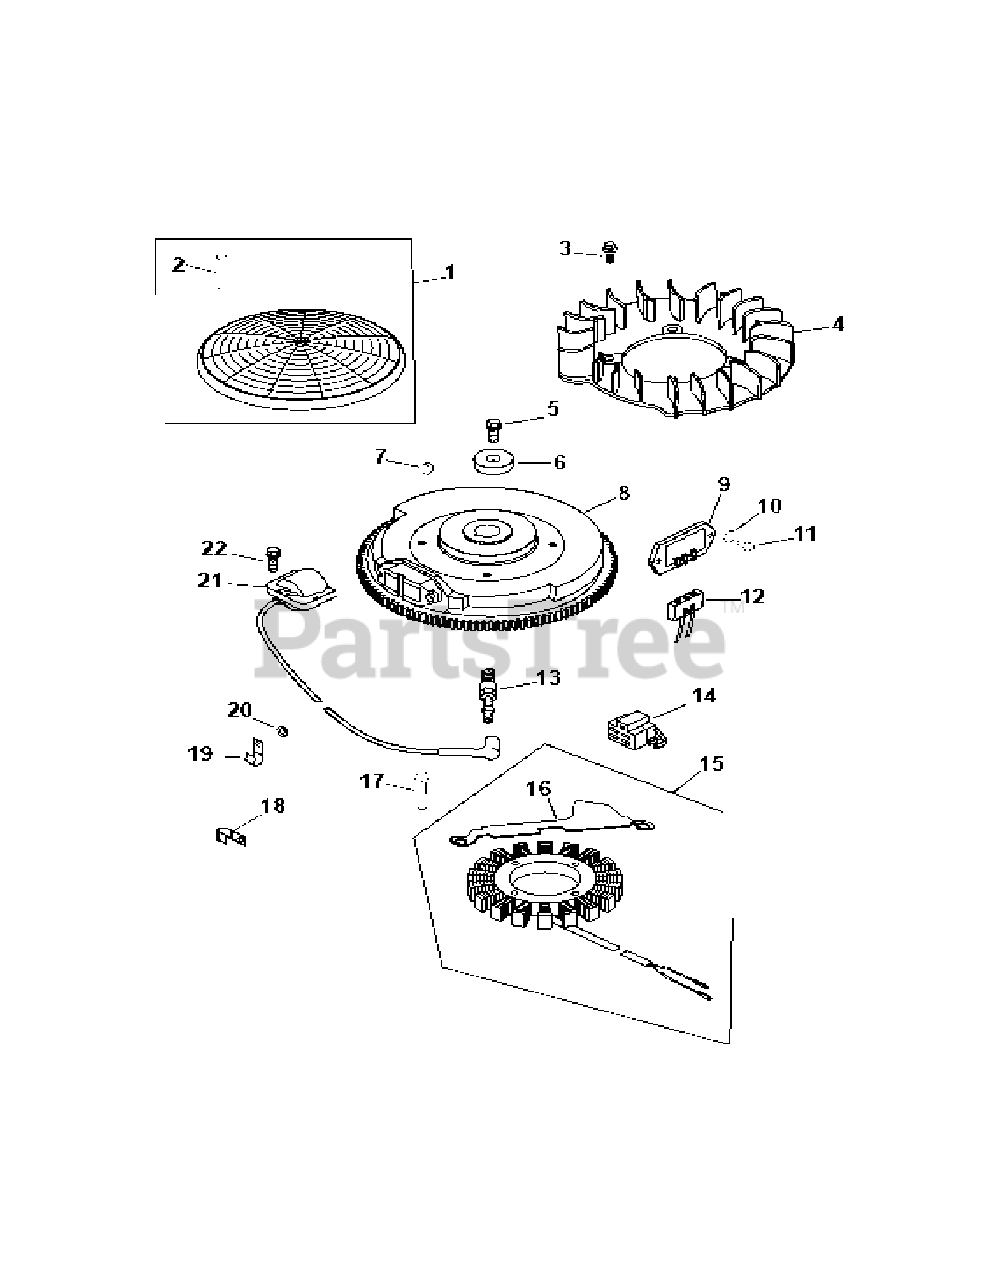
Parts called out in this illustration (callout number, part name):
1	Grass Screen Kit
3	Shoulder Bolt
4	Fan
5	Hex Flange Screw
8	Flywheel
9	Regulator Rectifier
11	Hex Head Screw
12	Connector
13	Spark Plug
15	15 amp Stator
16	Stator Wire Bracket
17	Hex Head Screw
18	Cable Clip
21	Ignition Module
22	Screw
